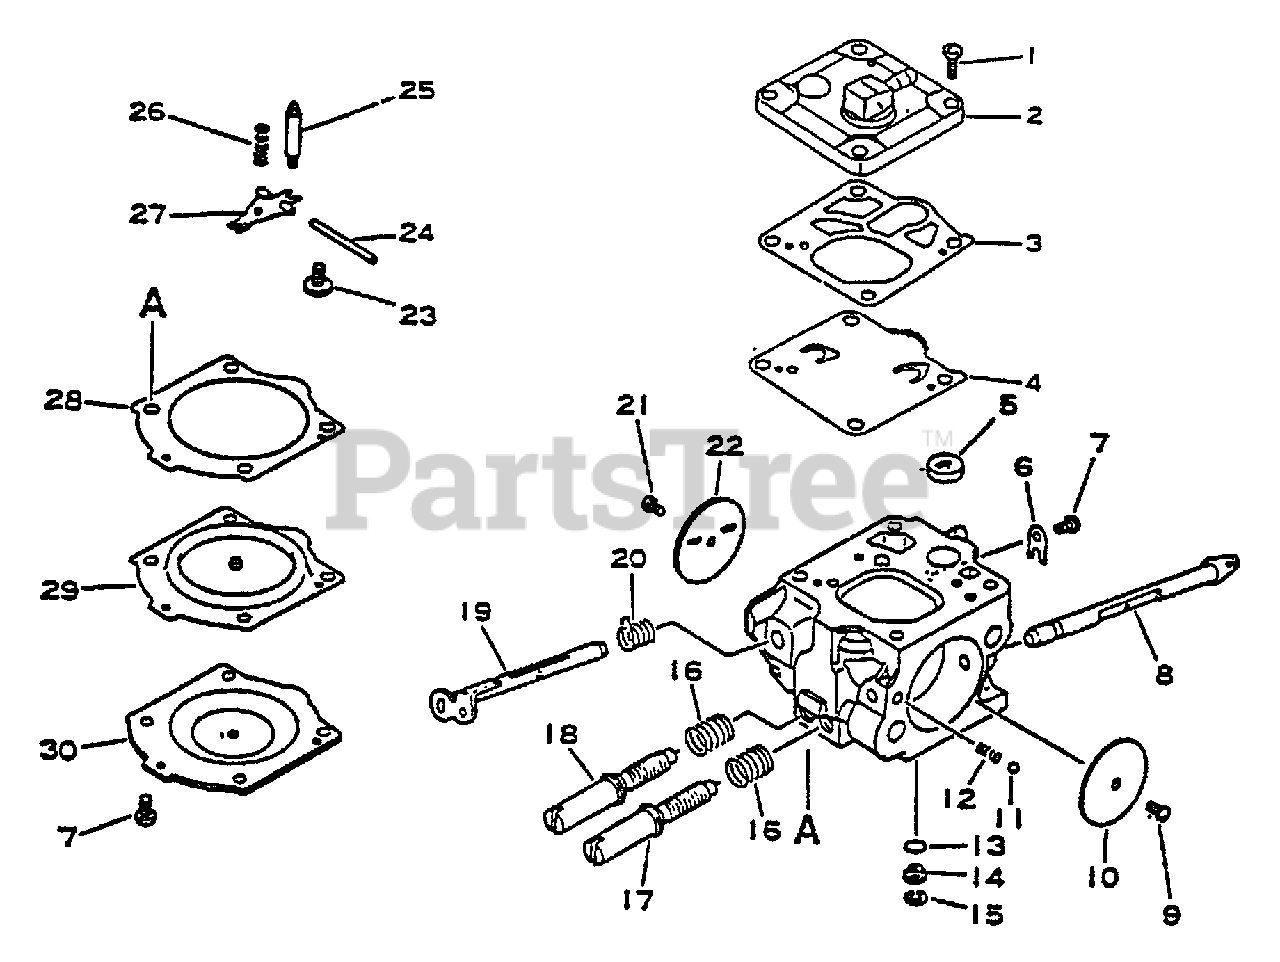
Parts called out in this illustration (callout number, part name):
1	SCREW
2	COVER, FUEL PUMP
3	GASKET, PUMP
4	DIAPHRAGM, PUMP
5	STRAINER
6	RING, RETAINING
7	SCREW
8	SHAFT, CHOKE
10	VALVE, CHOKE
11	BALL, CHOKE
12	SPRING, CHOKE
13	O-RING
15	WASHER
16	SPRING
17	NEEDLE, HIGH SPEED
18	NEEDLE, IDLE
19	SHAFT, THROTTLE
20	SPRING, THROTTLE RETURN
21	SCREW ASSY
22	VALVE, THROTTLE
23	SCREW, METERING LEVER PIN
24	PIN, METERING LEVER
25	VALVE, INLET NEEDLE
26	SPRING, METERING LEVER
27	LEVER, METERING
28	GASKET, METERING
29	DIAPHRAGM, METERING
30	COVER, METERING DIAPHRAGM
30	REPAIR KIT
30	GASKET / DIAPHRAGM KIT
